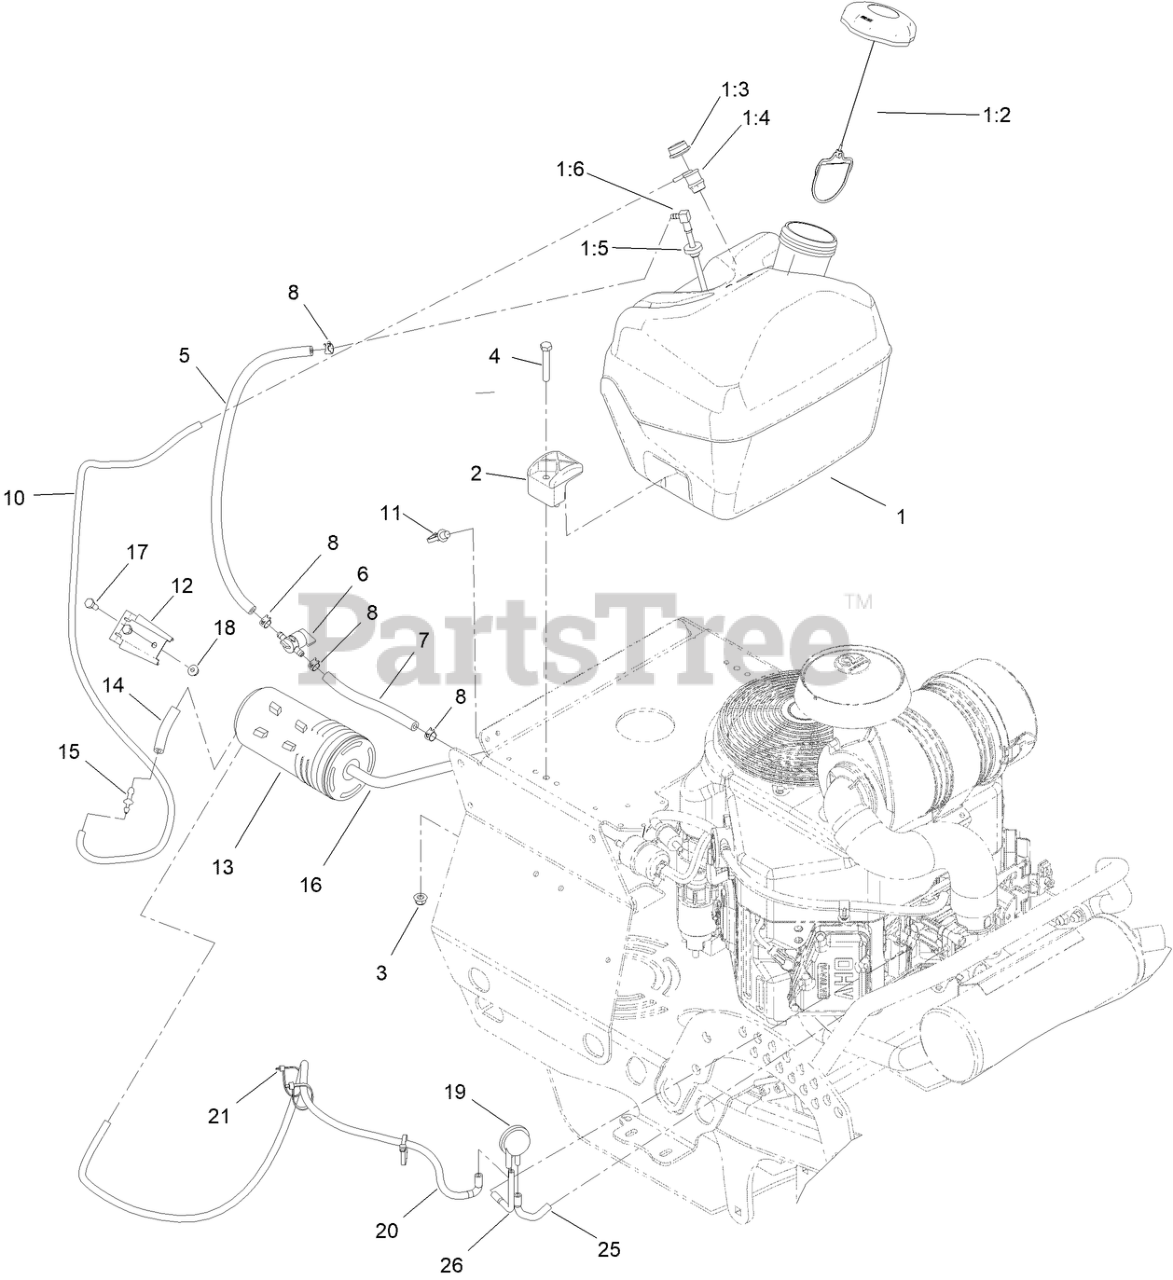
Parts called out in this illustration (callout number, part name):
1	FUEL TANK ASM, 5 GAL
1:2	CAP-FUEL, RATCHETING
1:3	GROMMET
1:4	VALVE-VENT, FUEL
1:5	BUSHING
3	NUT-HF, NI
4	SCREW-HH
5	HOSE-FUEL
6	VALVE-FUEL
7	HOSE-FUEL
8	CLAMP-HOSE
10	HOSE, EMISSIONS
11	CLIP-TIE
12	BRACKET-CANISTER, CARBON
13	CANISTER-CARBON, 800CC
14	HOSE-FUEL
15	FITTING-STRAIGHT
16	HOSE-VENT, CANISTER
17	SCREW-HH
18	NUT-HF
19	VALVE-CONTROL, VACUUM
20	HOSE,VENT,FORMED
21	TIE-CABLE
25	HOSE-VENT, FORMED
26	HOSE-VENT, FORMED
